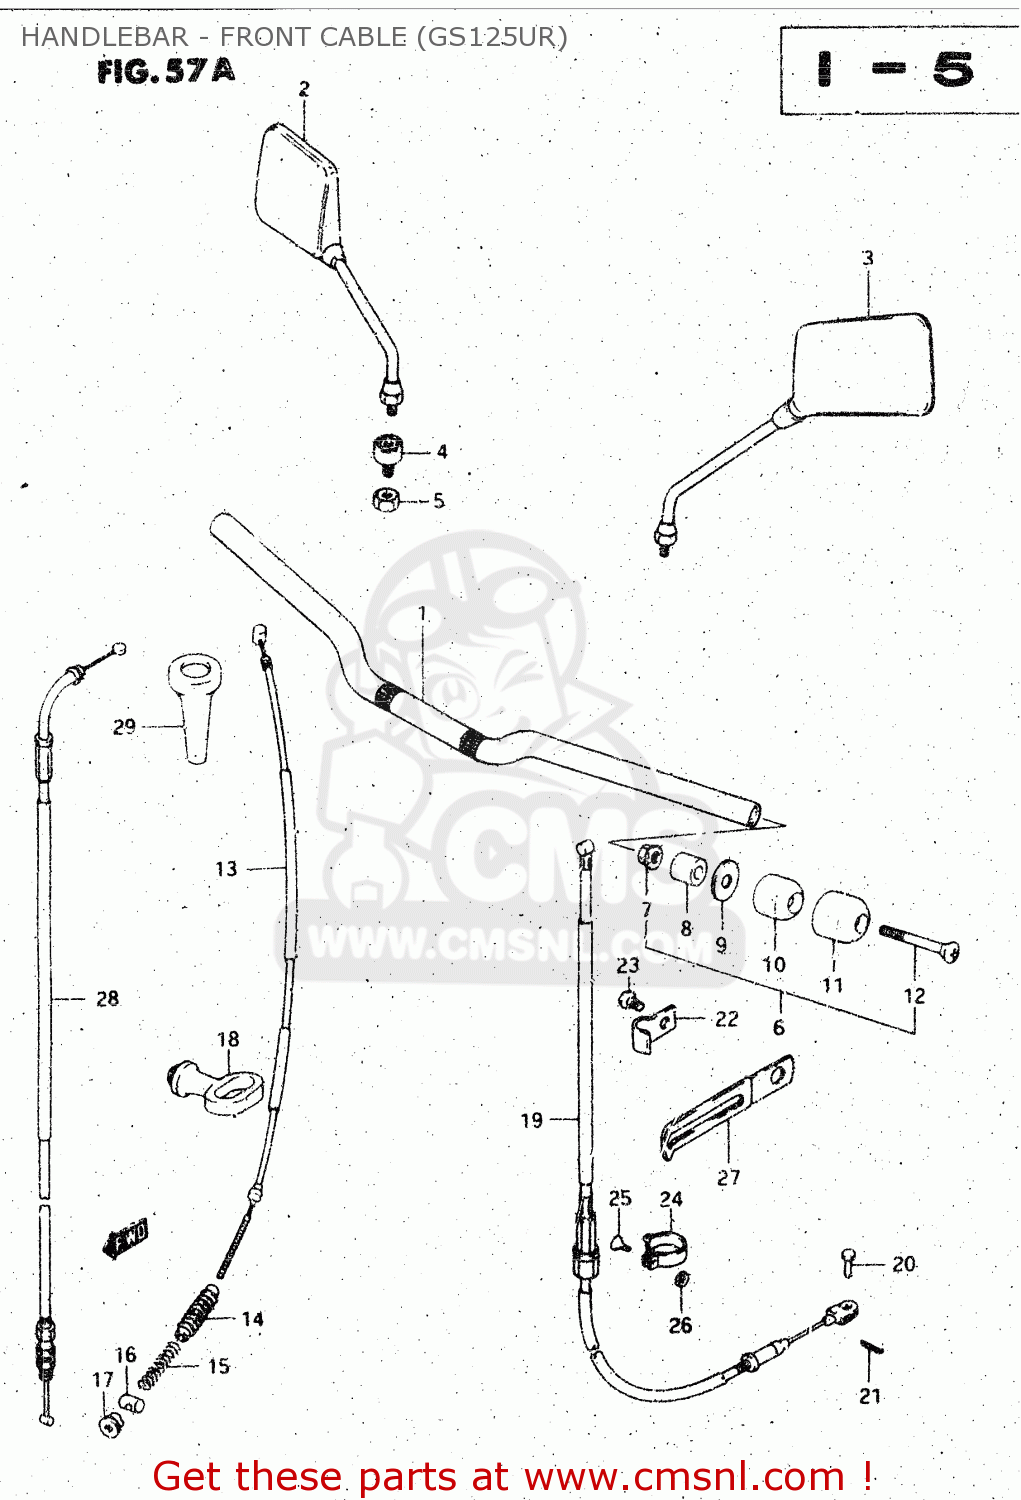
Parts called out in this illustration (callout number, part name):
1	HANDLEBAR
2	MIRROR ASSY, REAR VIEW RH
3	MIRROR ASSY, REAR VIEW LH
4	CUSHION ASSY,RR VIEW MIRROR
5	NUT
6	BALANCER SET,HANDLEBAR
7	NUT
8	EXPANDER,HANDLE BALANCER
9	SPACER,BALANCER
10	BALANCER,HANDLE
11	CAP,BALANCER
12	SCREW
13	CABLE,FR BRAKE
14	SEAL,DUST(7X16X75)
15	SPRING
16	PIN,10X19
17	NUT
18	GUIDE,CABLE
19	CABLE ASSY,CLUTCH
20	PIN(L:13)
21	PIN
22	CLAMP,CLUTCH CABLE NO.1
23	SCREW
24	CLAMP,CABLE
25	SCREW
26	NUT
27	CLAMP
28	CABLE ASSY,THROTTLE
29	BOOT,CLUTCH CABLE
